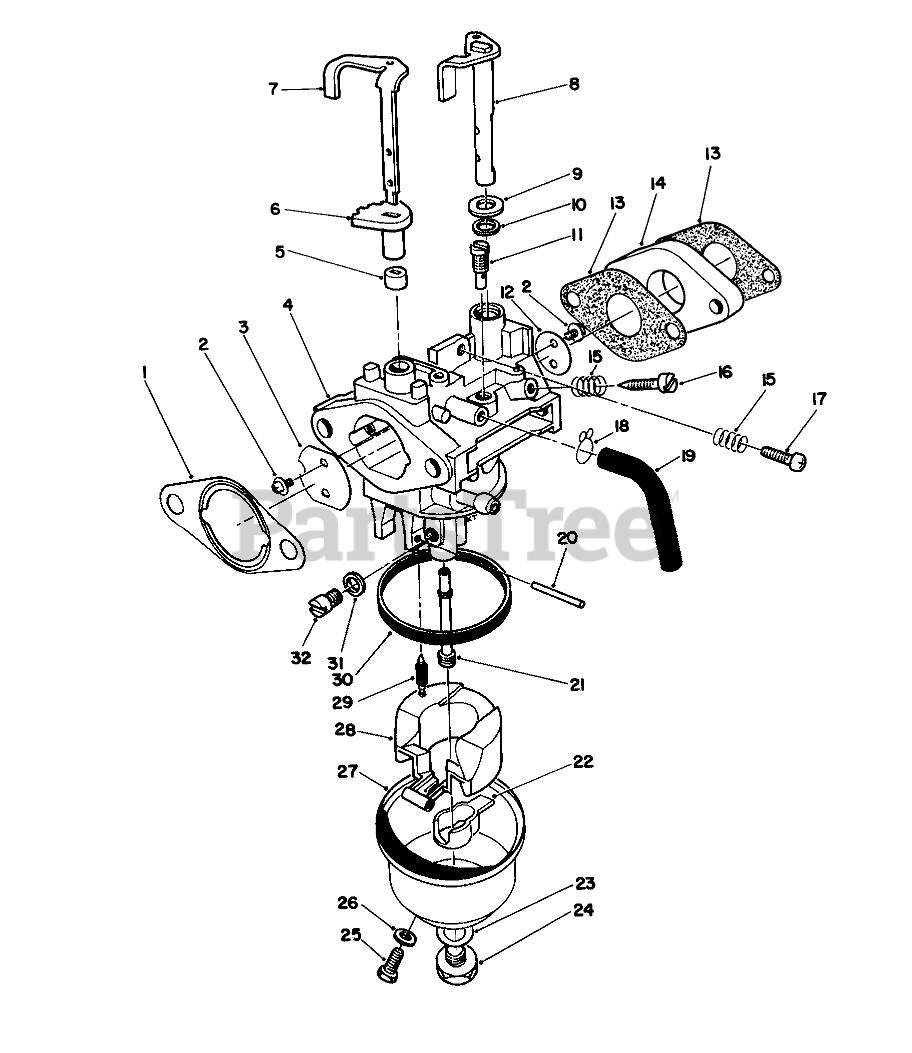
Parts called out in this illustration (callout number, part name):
1	GASKET F/W ENGINE
2	Screw
3	VALVE
4	Body-Carburetor
5	LOWER CHOKE RING
6	UPPER CHOKE RING
7	Shaft-Choke Valve
8	SHAFT
9	WASHER
10	Seal-Throttle Shaft
11	JET - PILOT
12	VALVE
13	GASKET INTAKE
14	INSULATOR - CARB.
15	SPRING-PILOT SCREW
16	ADJUSTER
17	SCREW
18	CLAMP
20	Pin
21	NOZZLE - MAIN
22	SPACER
23	GASKET
24	SCREW
25	SCREW
26	GASKET
28	FLOAT
29	NEEDLE
30	FLOAT BOWL GASKET
31	SPACER
32	JET - MAIN
